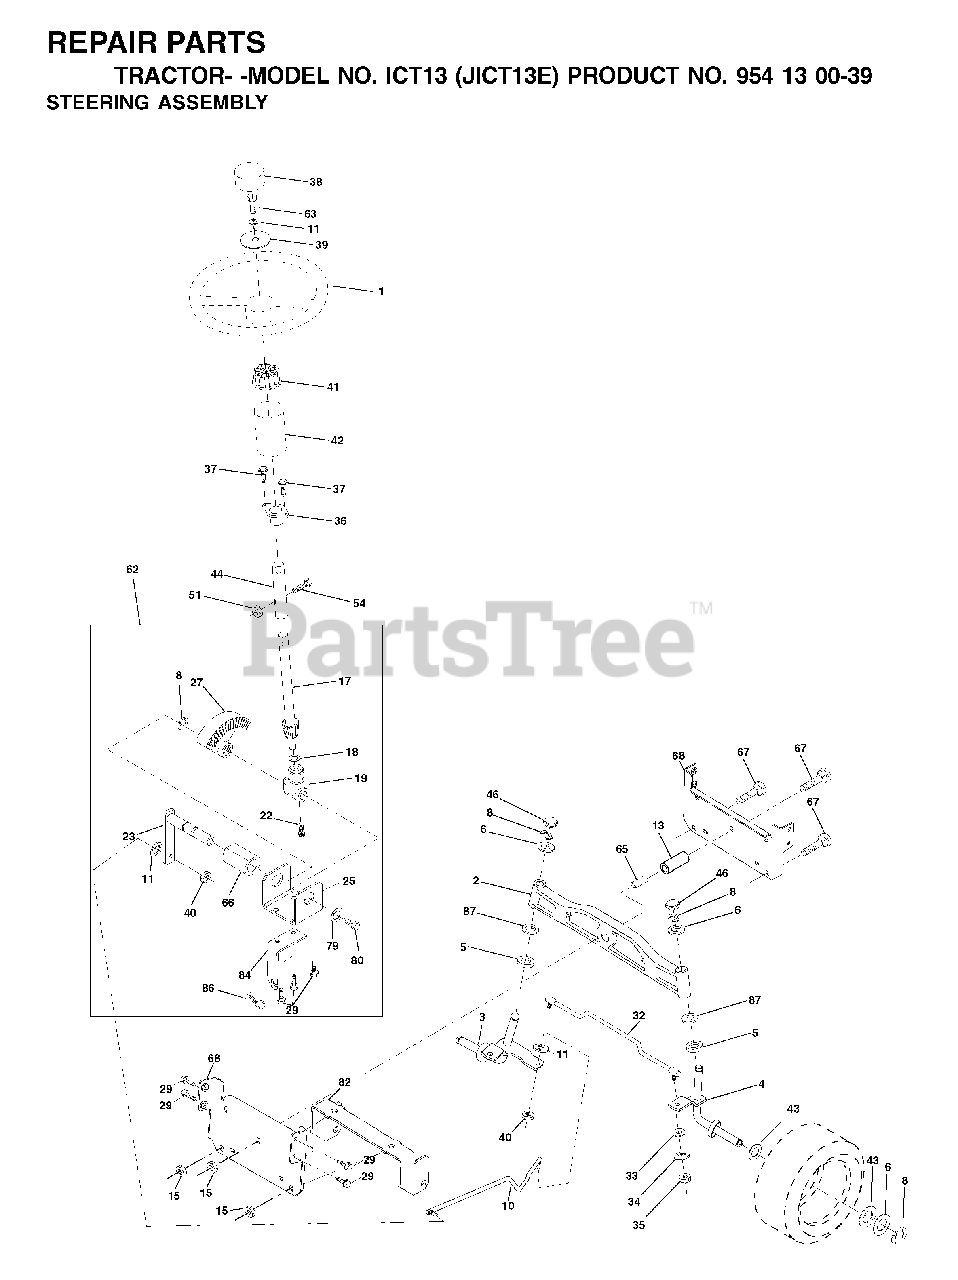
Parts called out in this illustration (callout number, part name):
2	AXLE ASM
3	SPINDLE.ASM.LH.15"TIRES
4	SPINDLE.ASM.RH.15"TIRES
8	RING CLIP
10	DRAGLINK.15".TIRES
11	WASHER, LOCK 3/8
13	TUBE, PIVOT AXLE
15	NUT
17	SHAFT ASM STEERING
18	THRUST WASHER
19	STEERING SHAFT SUPPORT
22	SCREW.HX.WSH.HD
23	SHAFT ASSY PITTMAN
25	BRACKET STEERING
27	GEAR.SECTOR
29	SCREW 3/8-16X3/4
32	ROD.ASM.TIE.BALL.JOINT.NOVAN
33	WASHER M
34	LOCKWASHER
35	NUT, CROWNLOCK
36	BUSHING, STEERING
39	WASHER 13/32 X 2-3/8 X 12 GA
40	GRIPCO NUT
41	STEERING WHEEL ADAPTOR
42	BOOT.STEERING.SHAFT.BLACK
44	EXT SHAFT STEERING
46	CAP.SPINDLE
51	NUT.71038.31-18.HEX.NYLOCK
54	BOLT.5/16-18X1-1/4 FULL.THREAD
65	SPACER BRACE AXLE
66	BEARING ARM
67	BOLT
68	BRACE.AXLE.15"TIRES
80	BOLT.HX.NYLON3/8-16X
82	BRACKET
86	SPRING.RETAINER.YELLOW.ZINC
87	WASHER, FLAT .781 X 1 1/2"
